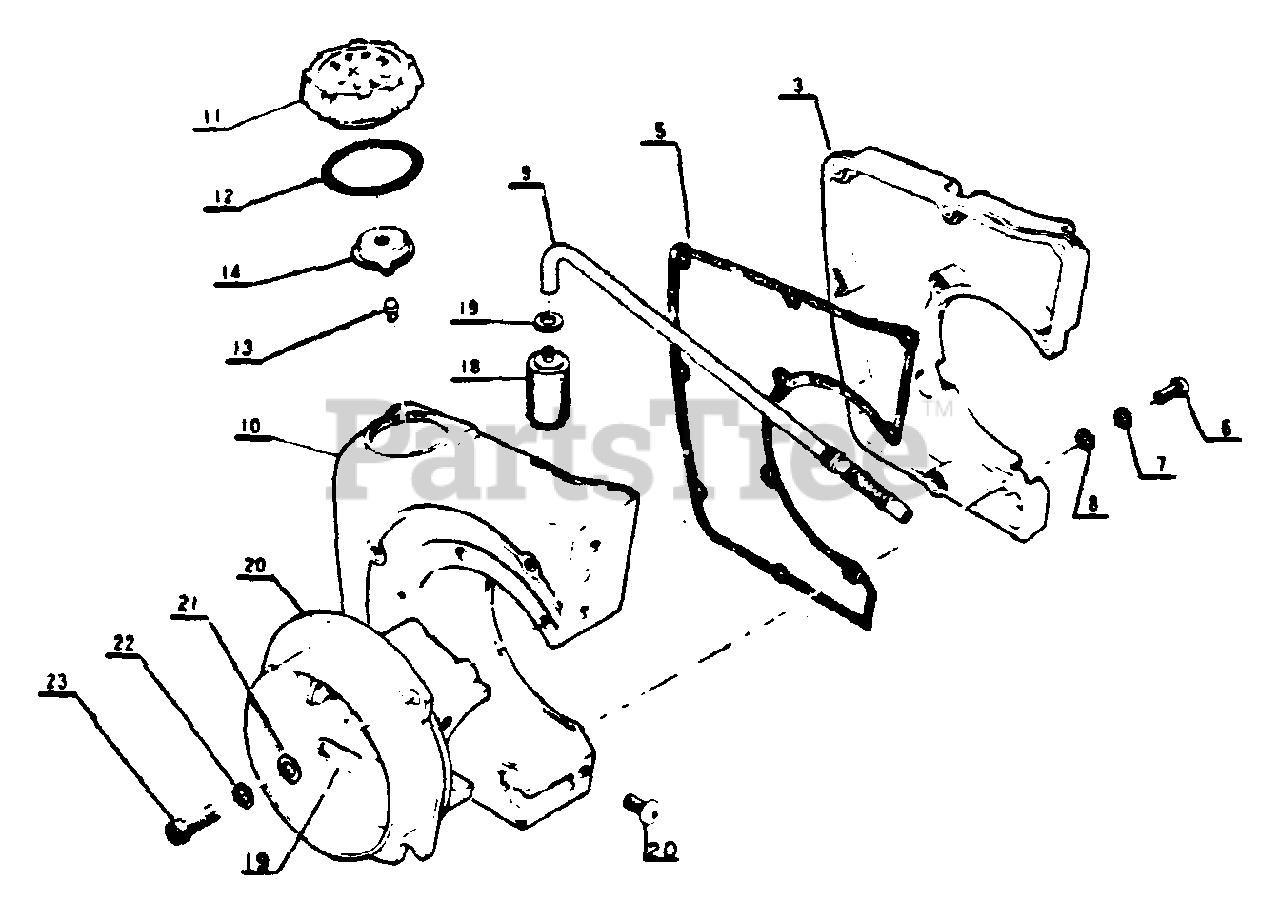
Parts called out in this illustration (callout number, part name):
3	LID, FUEL TANK
5	GASKET, FUEL TANK
6	SCREW - 4X12
7	LOCKWASHER - 4
8	WASHER - 4
9	PIPE - FUEL
10	TANK, FUEL
11	CAP
12	O-RING
14	HOLDER, VENT
18	FILTER, FUEL
19	WASHER - 6
20	CRANKCASE
21	WASHER - 5
22	LOCKWASHER - 5
23	BOLT
